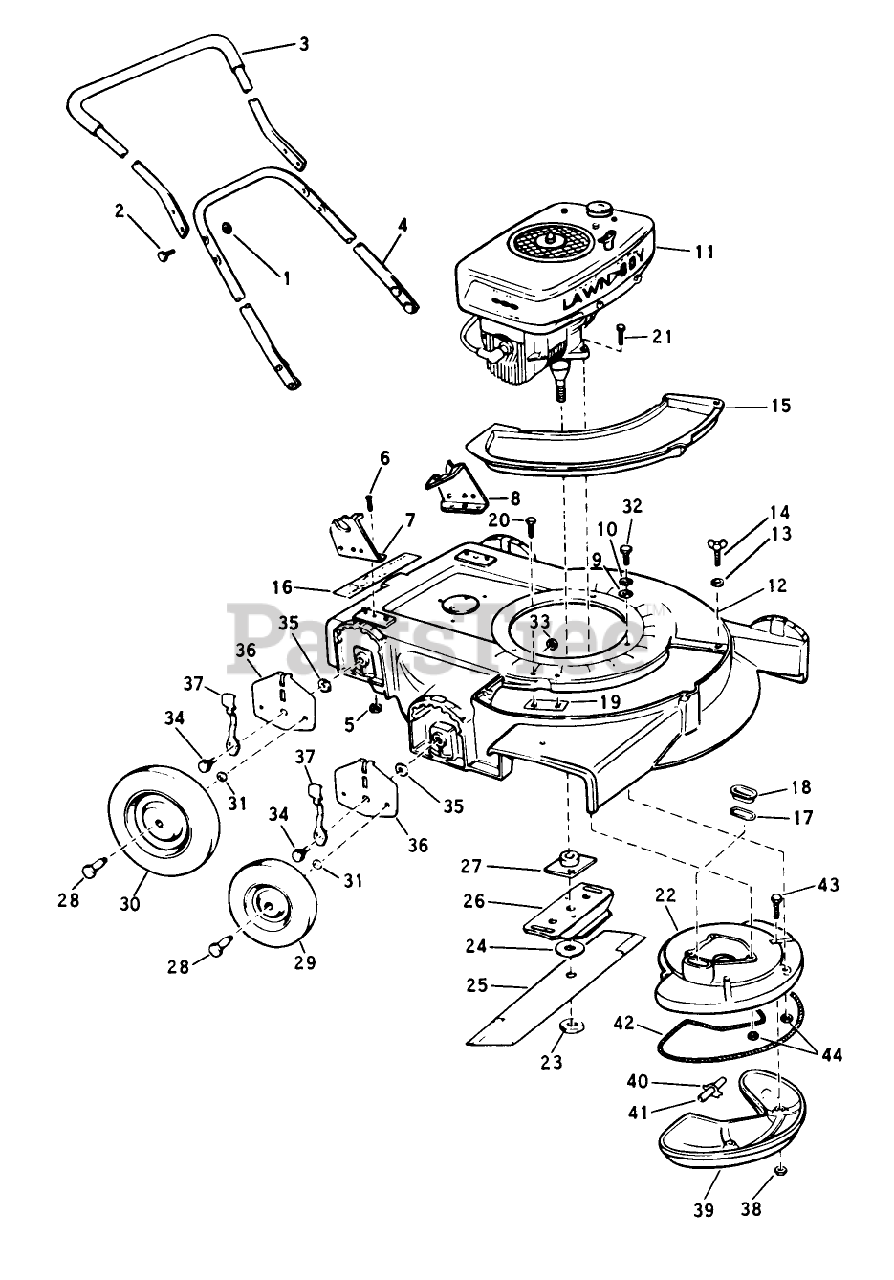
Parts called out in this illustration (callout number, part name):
1	STOP NUT
3	Handle Grip Assy. Top
6	SCREW S
12	Housing Cover Assy. 21"
16	Decal, Instruction
23	NUT-BLADE
27	PLATE AND COLLAR ASM
28	BOLT WHEEL
31	WASHER WROUGHT
38	LOCKNUT E
40	Gasket-Internal Tube
41	Tube-Internal Muffler
